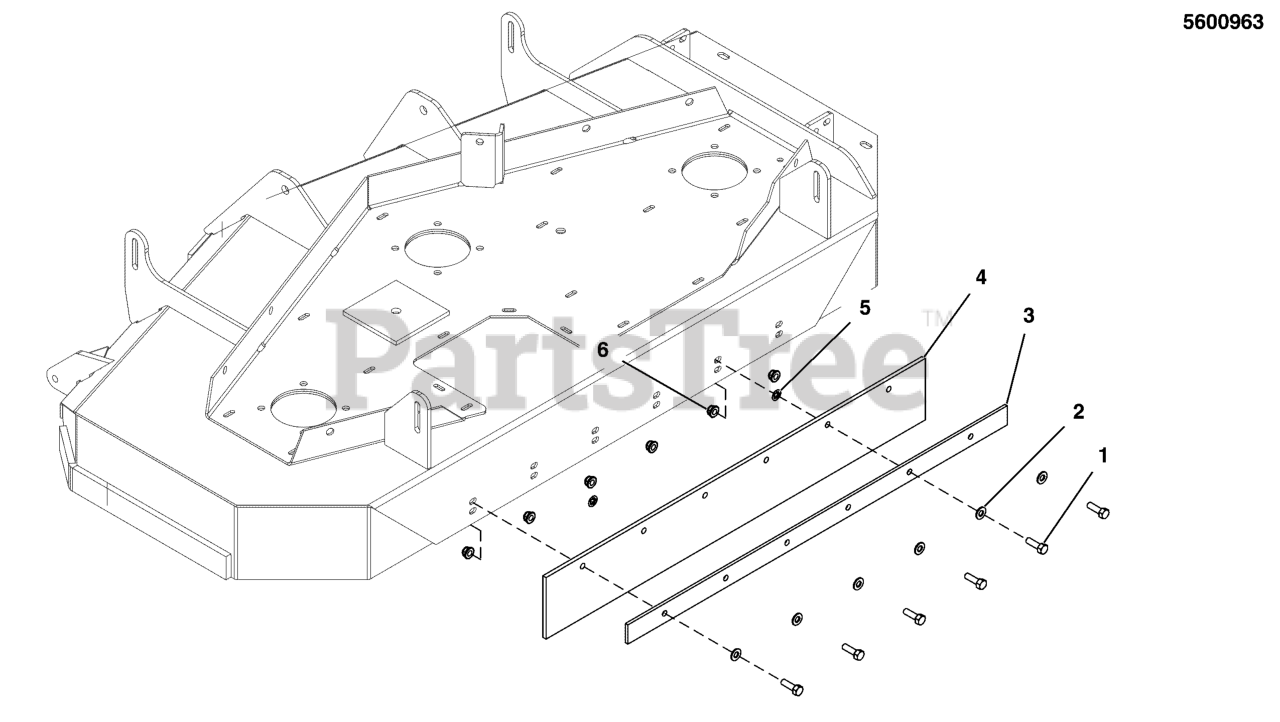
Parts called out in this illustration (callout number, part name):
1	BOLT, 5/16-18 X 1 GD5 CZ
2	WASHER, 5/16" SAE
3	PLATE, SUPPORT, 48 - BLK
4	FLAP, STRIPER, 48 DECK
5	5/16 PUSH-ON NUT RETAINER, STL, CZ
6	NUT, 5/16-18 HEX NYLOCK FLANGE
5600963	KIT STRIPER 44FN & 48ICD DECK
